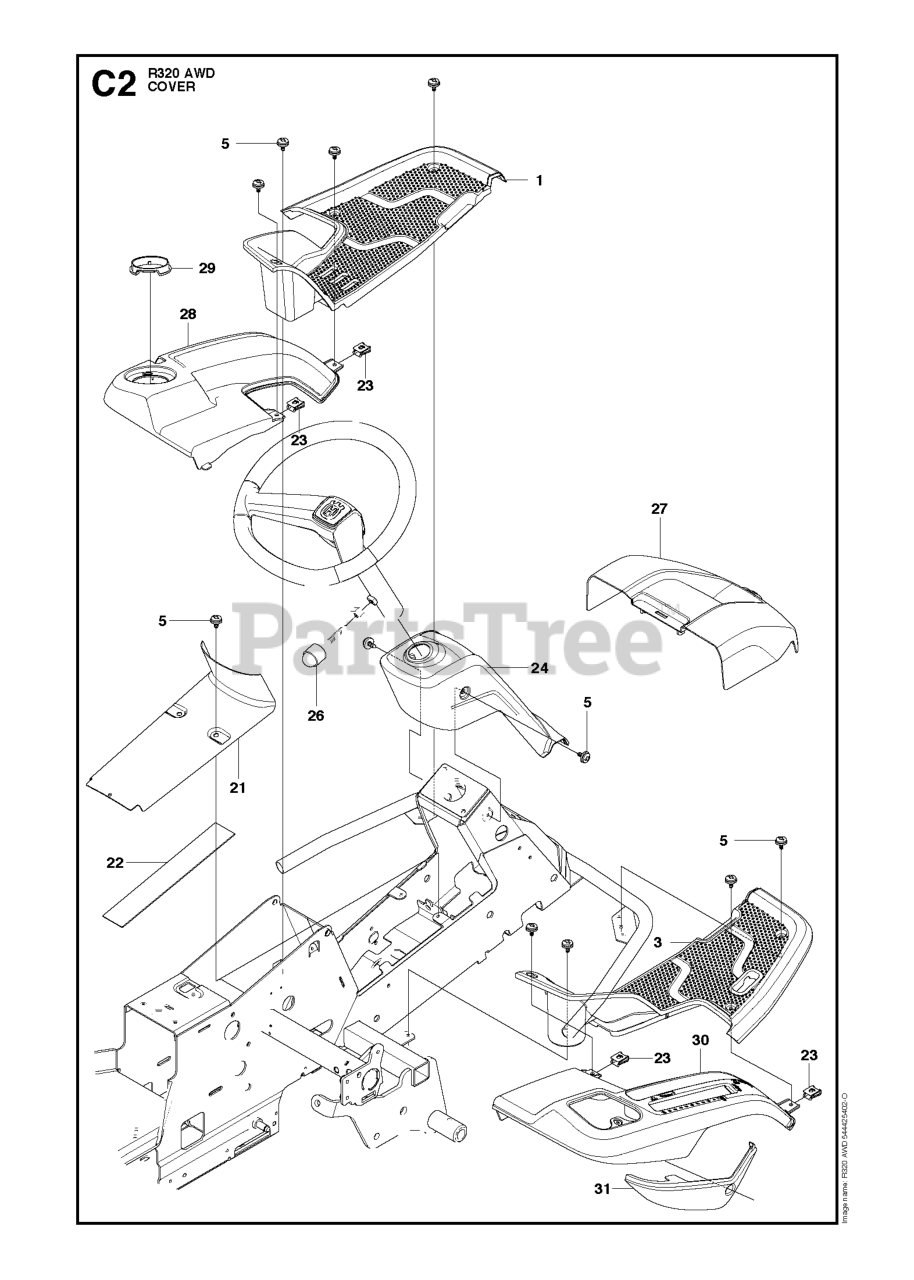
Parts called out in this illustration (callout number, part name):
1	FOOT PLATE
3	FOOT PLATE
26	PROTECTIVE COVER
27	UNIT COVER
29	LOCKING NUT
31	CONTROL COVER
